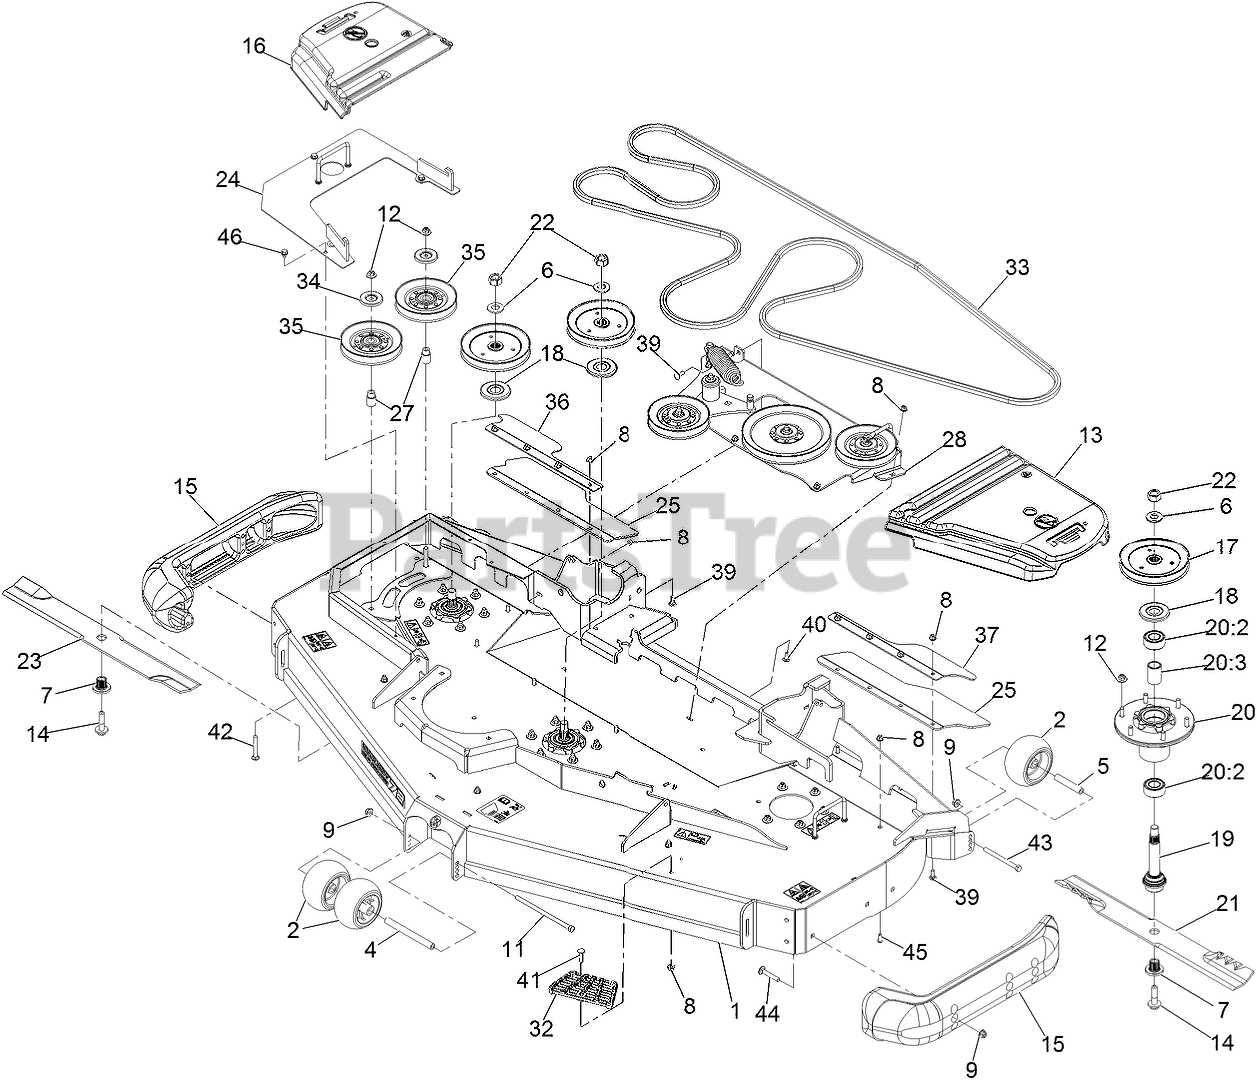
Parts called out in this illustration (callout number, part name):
1	Deck-Rd72 W/Decals
2	ROLLER-SCALP, ANTI
4	SPACER-WHEEL
5	TUBE-SPANNER
7	BUSHING,SPLINED
8	NUT-HF, NI
9	NUT-HF, NI
11	SCREW-HH
12	Nut-Nyloc 3/8-16 Flg
13	COVER-BELT, LH
14	SCREW,SEMS 1/2-20 X 2.19
15	SKID-BUMPER, DECK
16	COVER-BELT, RH
17	SHEAVE,BLADE DRIVE 6.50
18	GUARD-BEARING, TOP
19	ASM-SPINDLE AND SEAL
20	ASM-Cutter Hsg
20:2	Bearing-3205 Trashguard
20:3	Spacer-Bearing
22	NUT-HEX
24	COVER-REVERSE DRIVE
25	GUARD-TIRE
27	STANDOFF-IDLER
28	Idler Mount ASM
32	STEP-DECK
33	BELT-BB
34	SHIELD-DUST
35	IDLER V
36	SUPPORT-FLAP, OUTER (RH)
37	SUPPORT-FLAP, OUTER (LH)
39	SCREW-CARR
40	SCREW-CARR
41	Bolt-Carriage 5/16-18 X 1 1/4
42	SCREW-CARR
43	SCREW-HH
44	Bolt-Carriage 3/8-16 X 2 1/4
45	SCREW-HSBH
